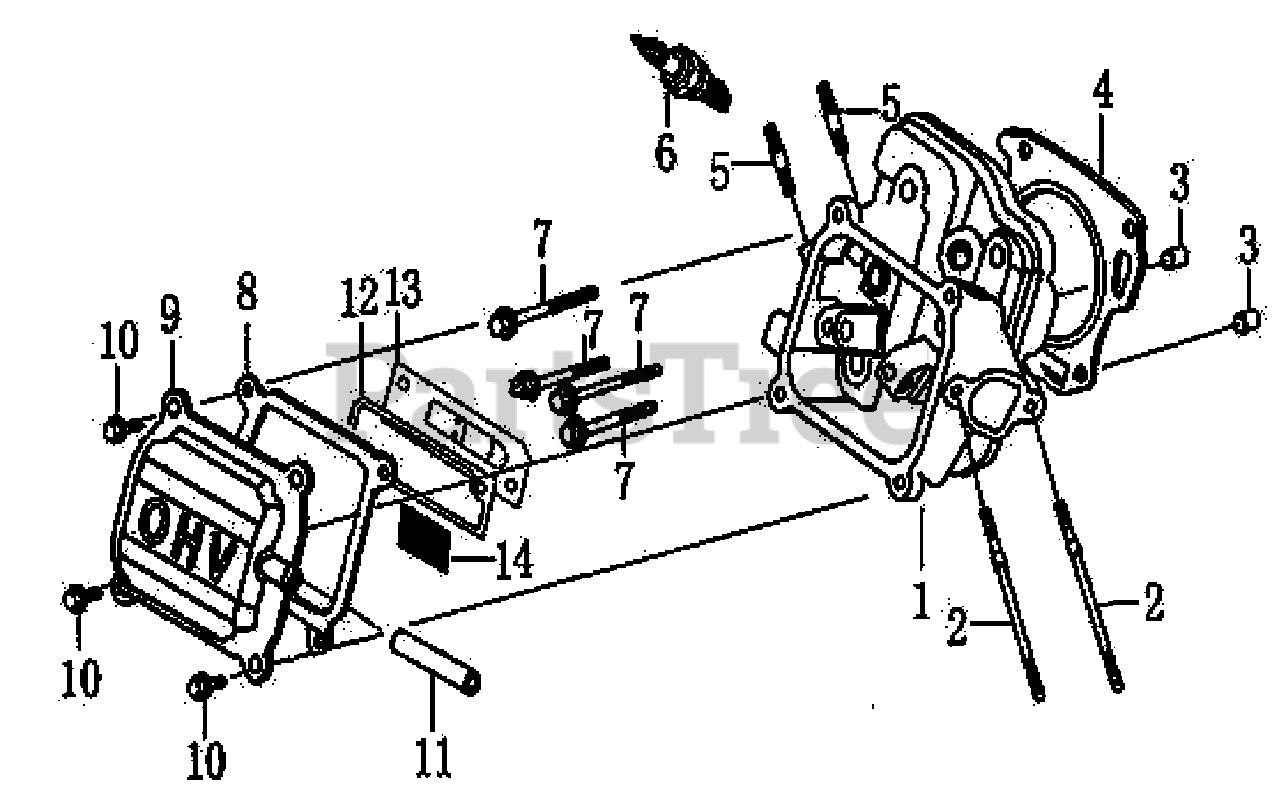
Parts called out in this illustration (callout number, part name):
1	HEAD, CYLINDER
2	BOLT, STUD, INTAKE
3	PIN, DOWEL
4	GASKET, CYLINDER HEAD
5	BOLT, STUD EXHAUST
6	PLUG, SPARK
7	BOLT, FLANGED HEAD, 8*60
8	GASKET, HEAD COVER
9	COVER, HEAD
10	BOLT, FLANGE , 6*14
11	TUBE, BREATHER
12	GASKET, BREATHER CHAMBER
13	CAP, BREATHER CHAMBER
14	STRAINER, OIL
